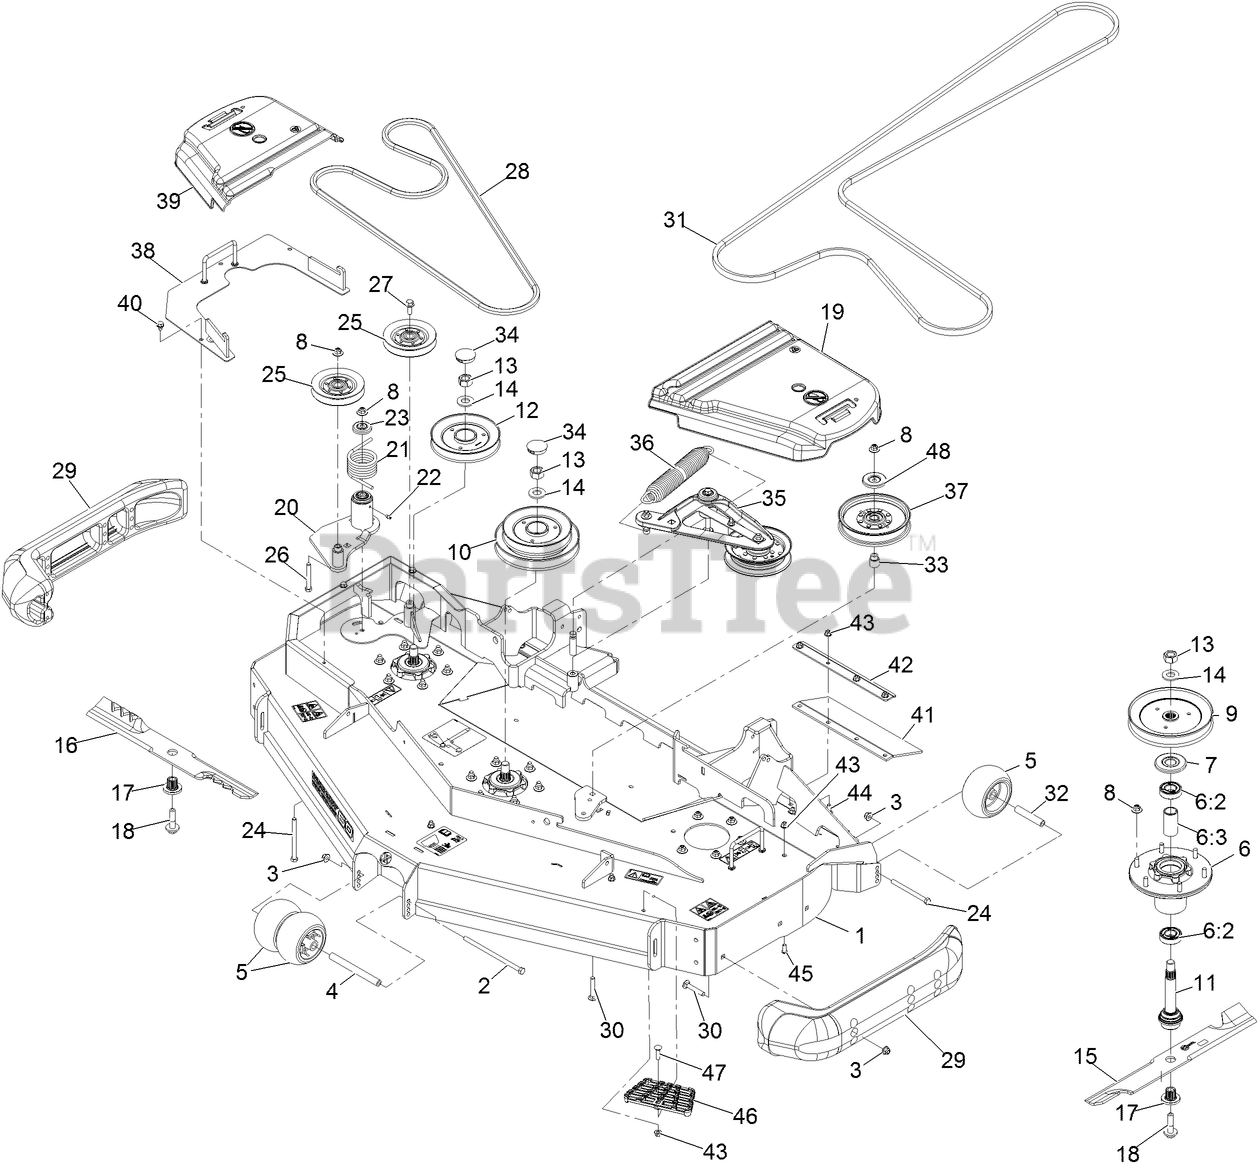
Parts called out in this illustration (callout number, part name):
1	DECK-RD60 NLZ, W/DECALS
2	SCREW-HH
3	NUT-HF, NI
4	SPACER-WHEEL
5	ROLLER-SCALP, ANTI
6	ASM-CUTTER HSG WITH BEARINGS
6:2	BEARING-BALL
6:3	SPACER-BEARING
7	GUARD,BEARING TOP .989
8	Nut-Nyloc 3/8-16 Flg
9	SHEAVE,BLADE DRIVE 7.25
10	SHEAVE, DOUBLE 60RD
11	ASM-SPINDLE AND SEAL
12	SHEAVE-RD REV DRIVE SERIES 4
13	NUT-HEX
15	Blade-Extreme 2, 20.50"
16	Blade-Low Lift 20.5, Rd60
16	Blade-Extreme 2-20.50, Rd60
17	BUSHING,SPLINED
18	SCREW,SEMS 1/2-20 X 2.19
19	COVER-BELT, LH
20	IDLER ASM
21	SPRING-TORSION
22	FITTING-GREASE
23	GUARD-TOP
24	SCREW-HH
26	SCREW-HH
27	SCREW-HHF
28	BELT
29	SKID-BUMPER, DECK
30	Bolt-Carriage 3/8-16 X 2 1/4
31	BELT
32	TUBE-SPANNER
33	BUSHING-IDLER
34	PLUG,BLACK NYLON 1.75
35	DECK IDLER ASM
36	SPRING-EXTENSION
37	IDLER-PULLEY, FLAT 6.00X1.00
38	COVER-DRIVE REVERSE
39	COVER-BELT, RH
41	GUARD-TIRE
42	SUPPORT-OUTER FLAP
43	NUT-HF, NI
44	SCREW-CARR
45	SCREW-HSBH
46	STEP-DECK
47	Bolt-Carriage 5/16-18 X 1 1/4
48	SHIELD-DUST
